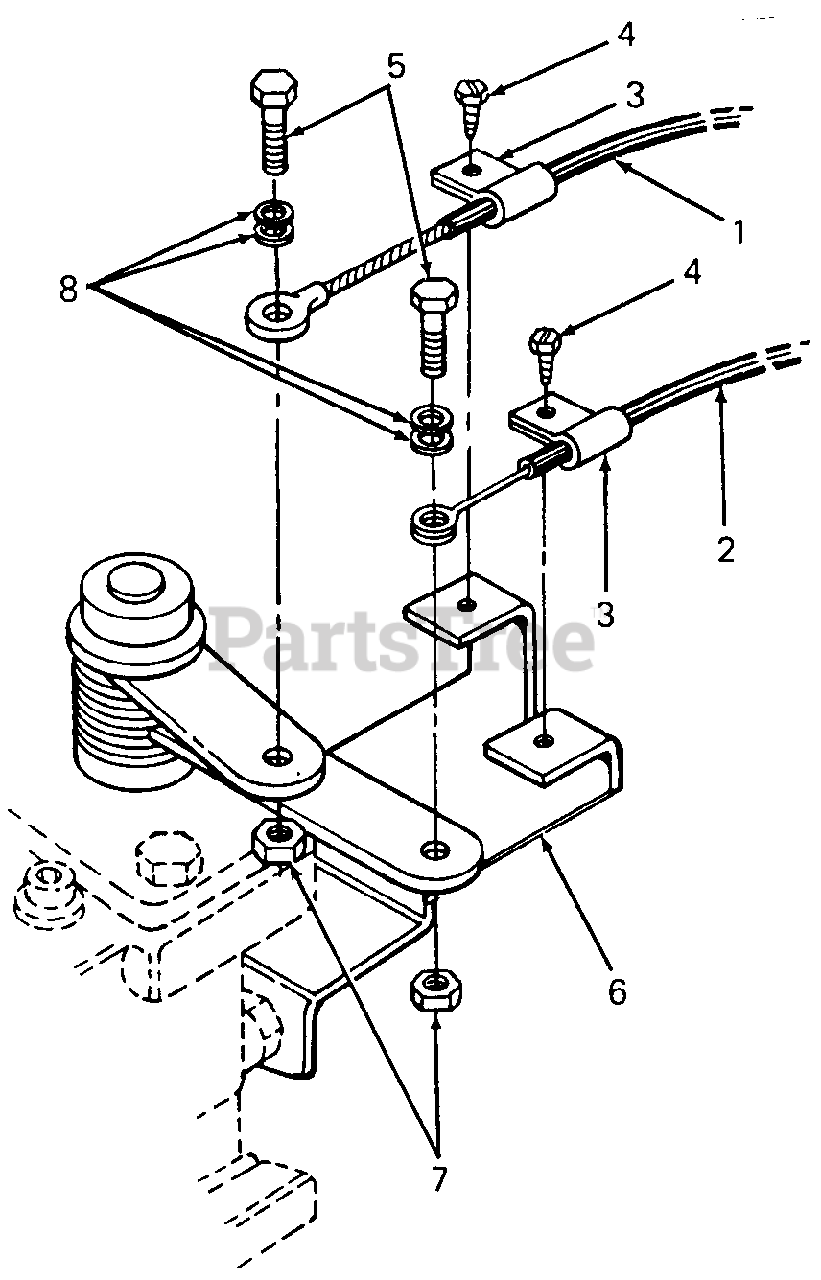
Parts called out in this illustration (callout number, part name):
1	Cable, Shut-Off
2	Cable, Throttle
3	Clamp, Conduit
4	Screw, Hex "B" Tapp, #10 X .62 Lg
5	Screw, Hex Cap, 5/16-18 X .75 Lg GR5
6	Bracket, Control
7	Nut, Hex Center Lock, 5/16-18 GR5
8	Washer, Flat, .344 X .62 X .063 Thk
